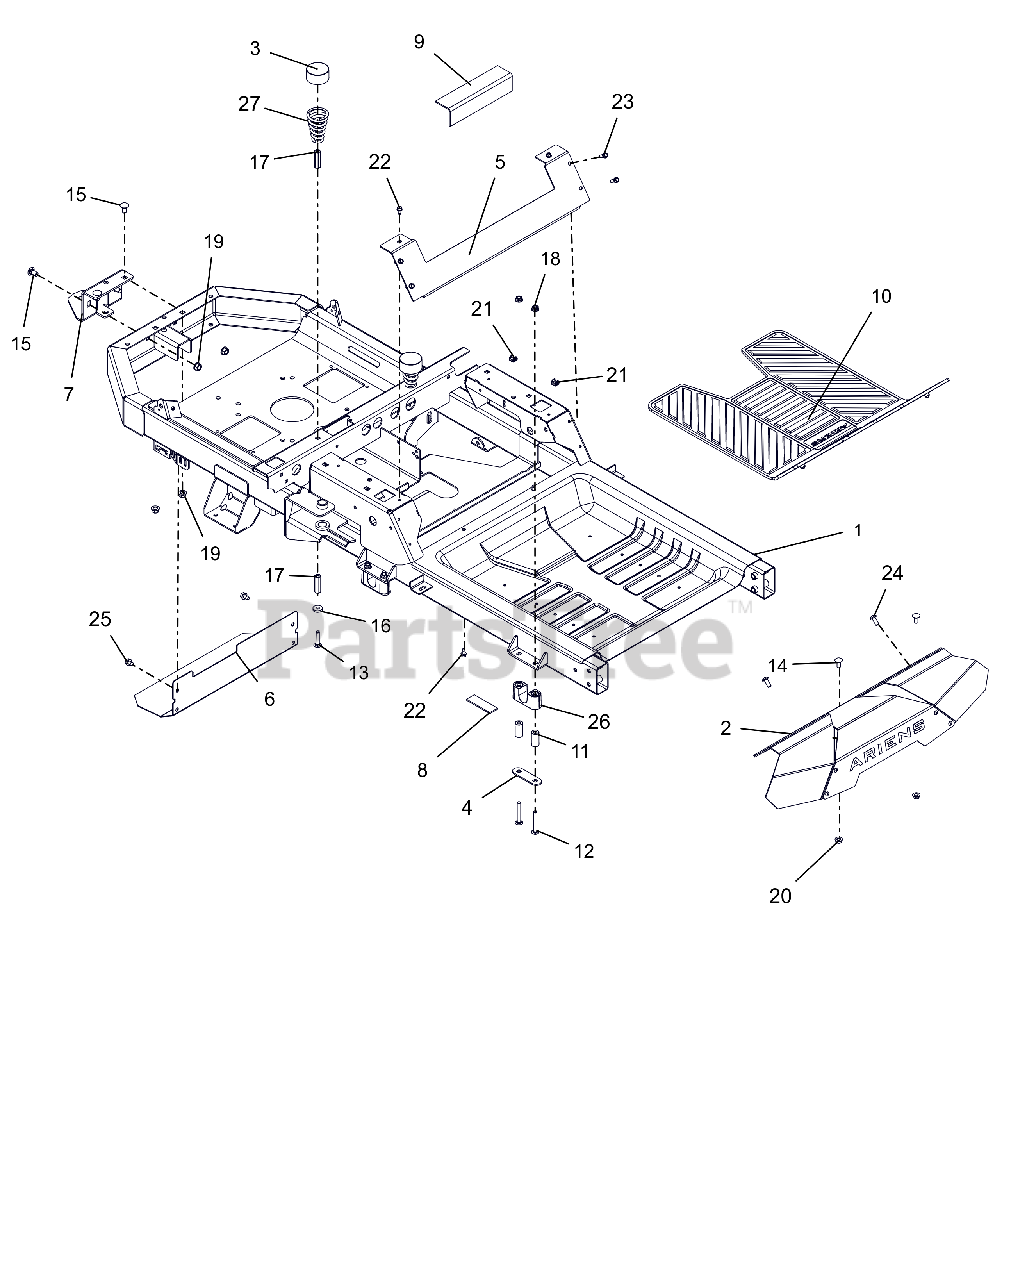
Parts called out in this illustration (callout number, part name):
1	KIT, IKON-X/XL FRAME (2016)
2	KIT, IKON FOOT REST W/DECAL
3	HUB CAP
4	PLATE, BEARING SUPPORT
5	PLATE, SEAT KICK
6	HEAT, SHIELD
7	BRKT, HITCH TONGUE
8	PAD,RBR 1.0"X3.0" W/ADHESIVE
9	PAD, RUBBER-TANK
10	FLOOR MAT, RUBBER - ARIENS
11	SPACER, .323 X .698 X 1.441
12	BLT-RDHDSQSHNK .31-18X2.25 YWZ
13	@BLT-RDHDSQNK .31-18X1.50 G5YZ
14	@BLT-RDHDSQNK .31-18X.75 G5YZ
15	@BLT-RDHDSQNK .38-16X.75 G5YZ
16	WSHR-FL-STL .328X.87X.179 YWZC
17	NUT, COUPLING 5/16-18 X 1 3/4
18	@NUT-LK-CTR-FLG .31-18 YZ GR F
19	@NUT-LK-TOP-FLG .38-16 YWZC
20	@NUT-LK-TOP-FLG .31-18 YWZC
21	NUT RETNR .25-20
22	SCR-TAP .25-20X.50 HWH TR YWZ
23	SCR-TAP-PM .25-20X.75 TR YWZ
24	SCR-RDHDSKTAP .31-18 X .75
25	@SCR-TAP .31-18X.50 HWH TR YWZ
26	BSHG, DECK LIFT PIVOT
27	SPRING, SEAT
